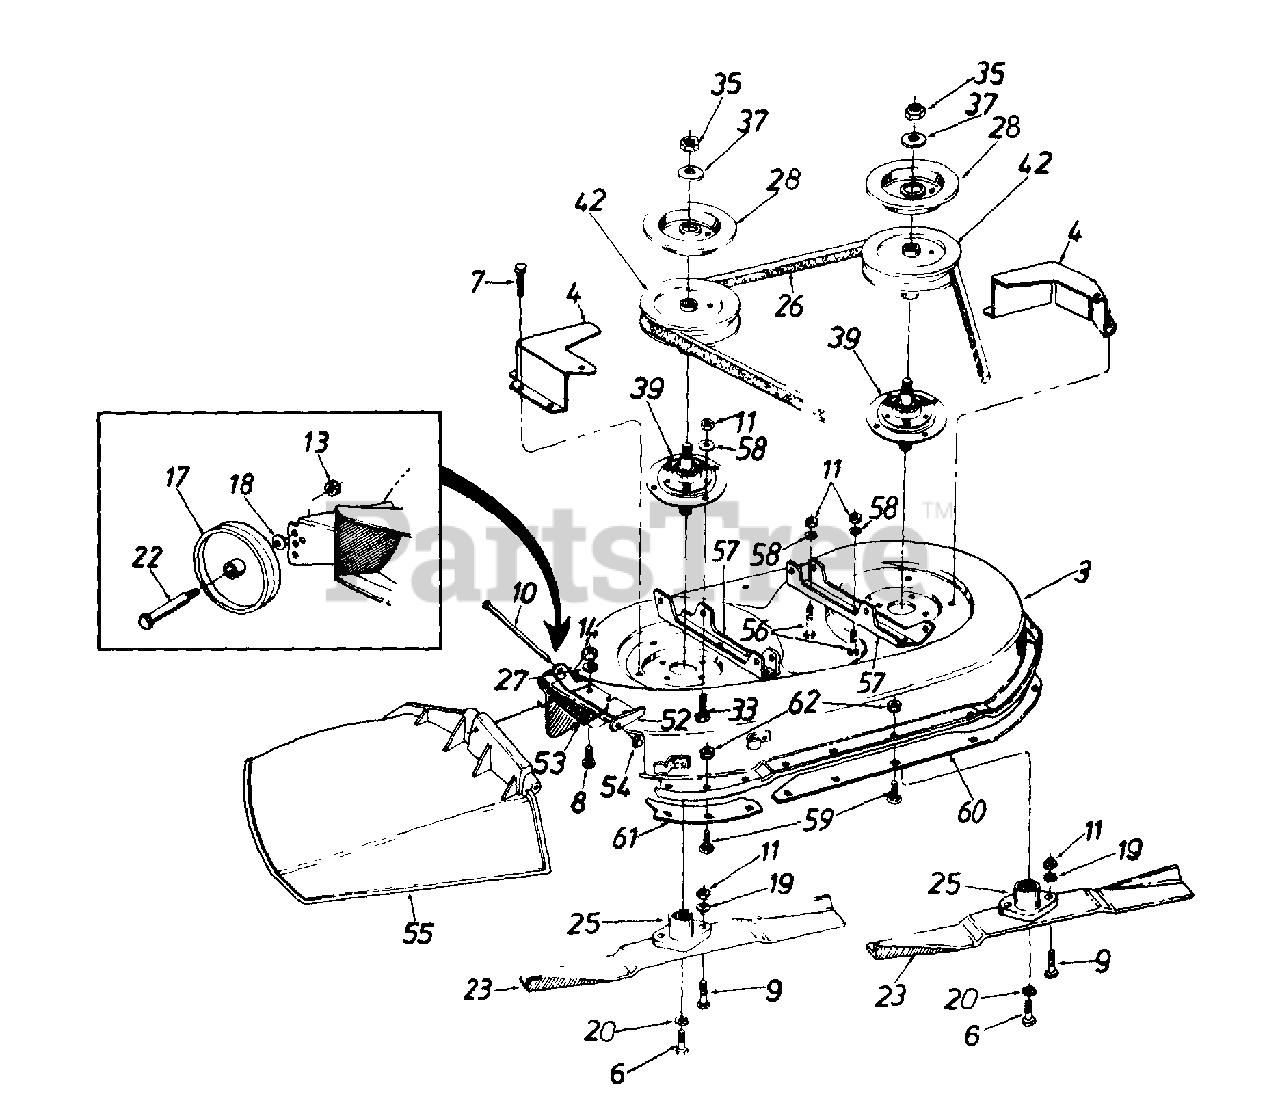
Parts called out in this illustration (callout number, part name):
6	Hex Bolt 3/8-24 x 1.0" Lg.
7	Hex Wash. Hd. TT-Tap Scr. 1/4-20 x .5" Lg.
8	Hex Bolt 1/4-20 x .62"
9	Hex Bolt Special 5/16-24 x 1.0"
10	Hinge Pin
11	Hex Nut 5/16-24 Thd.
13	Hex Top L-Nut 3/8-16 Thd.
14	Hex Nut 1/4-20 Thd.
17	Deck Wheel - 5"
18	Bell-Wash. .40" I.D. x .88" O.D.
19	L-Wash. 5/16" I.D.
20	L-Wash. 3/8" I.D. - H.D.
22	Shld. Bolt .498" Dia. x 1.53"
23	High-Lift Blade
25	Blade Adapter
26	V-Belt
27	Bell-Wash. 1/4" I.D.
28	Brake Disc
33	Hex Bolt 5/16-24 x .75" Lg.
35	Hex Jam Nut 5/8-18 Thd.
37	L-Wash. 5/8" I.D.
39	Blade Spindle Ass'y Comp.
42	5.5" Dia. Pulley
52	Hinge Mtg. Brkt.
53	Torsion Spring
54	Push Nut
55	Chute Ass'y. Comp.
56	Hex Bolt 5/16-24 x .75" Lg.
59	Carr. Bolt 1/4-20 x 5" Lg.
62	Hex Sems Nut 1/4-20 Thd.
